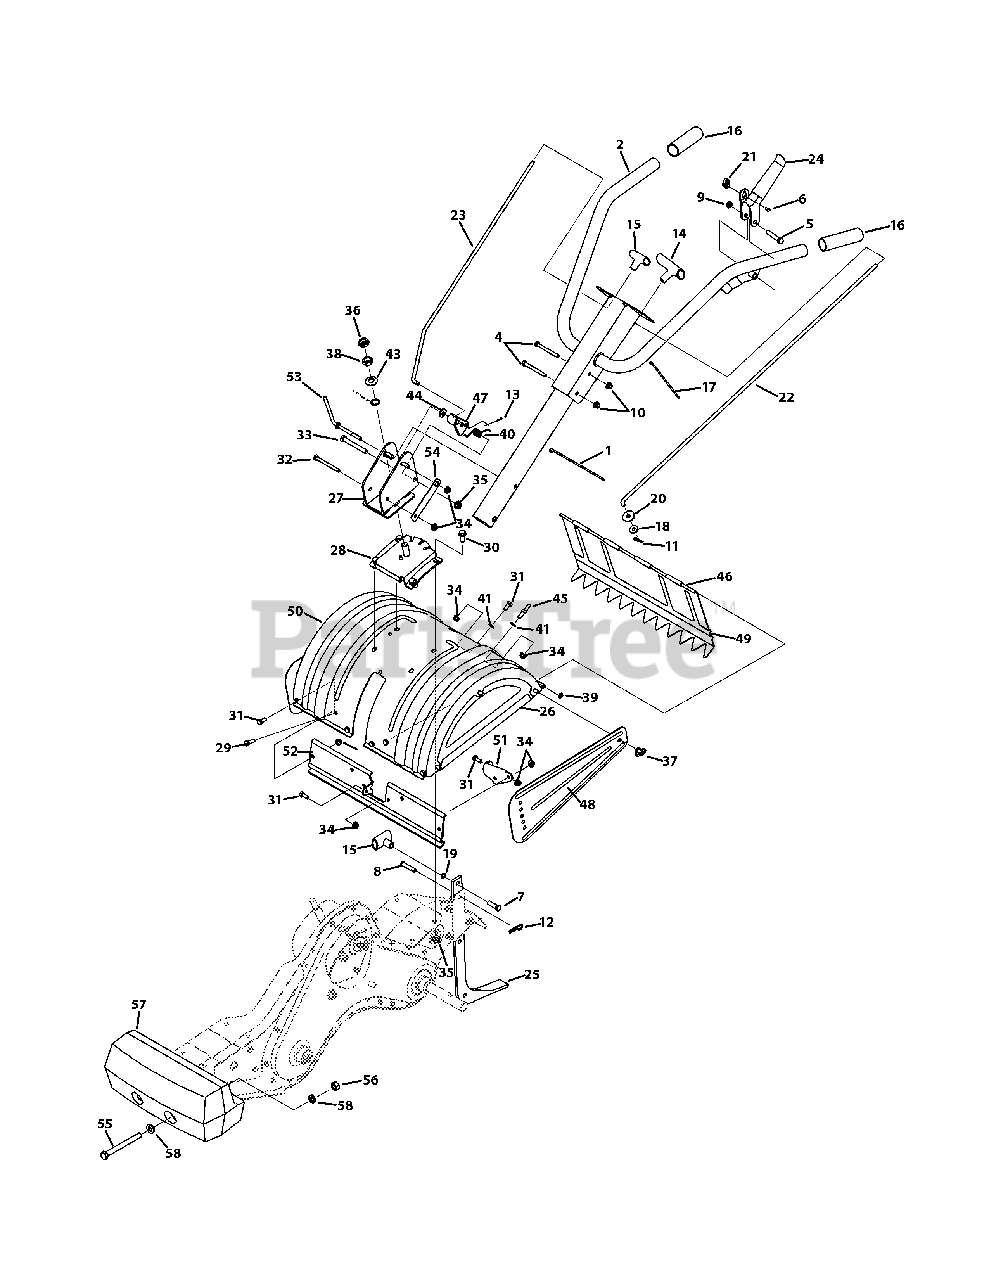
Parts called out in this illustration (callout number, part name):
1	Cable Tie
2	Upper Handle Assembly
2	Lower Swing Handle Tube Assembly
4	Hex Screw, 5/16-18 x 3.00
5	Hex Screw, 3/8-24 x 2.25
6	Hex Screw, #10-16 x 0.440
7	Hex Screw, 3/8-16 x 1.25
8	Clevis Pin, 3/8 x 1.75
9	Jam Lock Nut, 3/8-24
10	Flange Lock Nut, 5/16-18
11	Cotter Pin, .072 x 1.13
12	Cotter Pin, .125 x 1.75
13	Cotter Pin, 3/32 x .750
14	T-Knob
15	T-Knob
16	Round Grip
17	Cable Tie, 3/16 x .05 x 7.4
18	Rubber Washer, .33 x .87 x .125
19	Flat Washer, .385 x .620 x .033
20	Flat Washer, .411 x 1.25 x .100
21	Cable Barrel Holder
22	Clutch Rod
23	Clutch Rod
24	Clutch Assembly Lever
25	Tiller Depth Control
26	End Cover Assembly
27	Handle Pivot Bracket Assembly
28	Handle Pivot Base Bracket Assembly
29	Hex Screw, 5/16-18 x 1.00
30	Hex Washer Screw, 3/8-16 x .875
31	Hex Screw, 5/16-18 x .75
32	Hex Screw, 5/16-18 x 3.25
33	Hex Screw, 3/8-16 x 3.25
34	Flange Lock Nut, 5/16-18
35	Flange Lock Nut, 3/8-16
36	Jam Lock Nut, 5/8-18
37	Wing Nut w/ Bell Washer, 5/16-18
38	Jam Nut, 5/8-18
39	Cap Speed Nut, 1/4
40	Torsion Spring, .415 x .95
41	Flat Washer, .344 x .62 x .033
42	Flat Washer, .635 x .930 x .033
43	Bell Washer, .63 x 1.25 x .18
44	Flat Washer, .406 x .875 x .105
45	Hex Screw, 5/16-18 x .75
46	Tiller Flap Rod
47	Swing Handle Link
48	Side Shield
49	Rear Tine Shield
50	Tine Shield
51	Front Tine Shield Bracket
52	Front Tine Shield Scraper Bracket
53	Handle Adjustment Crank
54	Hex Flange Retainer Bracket
55	Hex Screw, 1/2-13 x 5.00
56	Hex Nut, 1/2-13
57	40 lb. Counterweight
58	Flat Washer, .510 x 1.000 x .125
